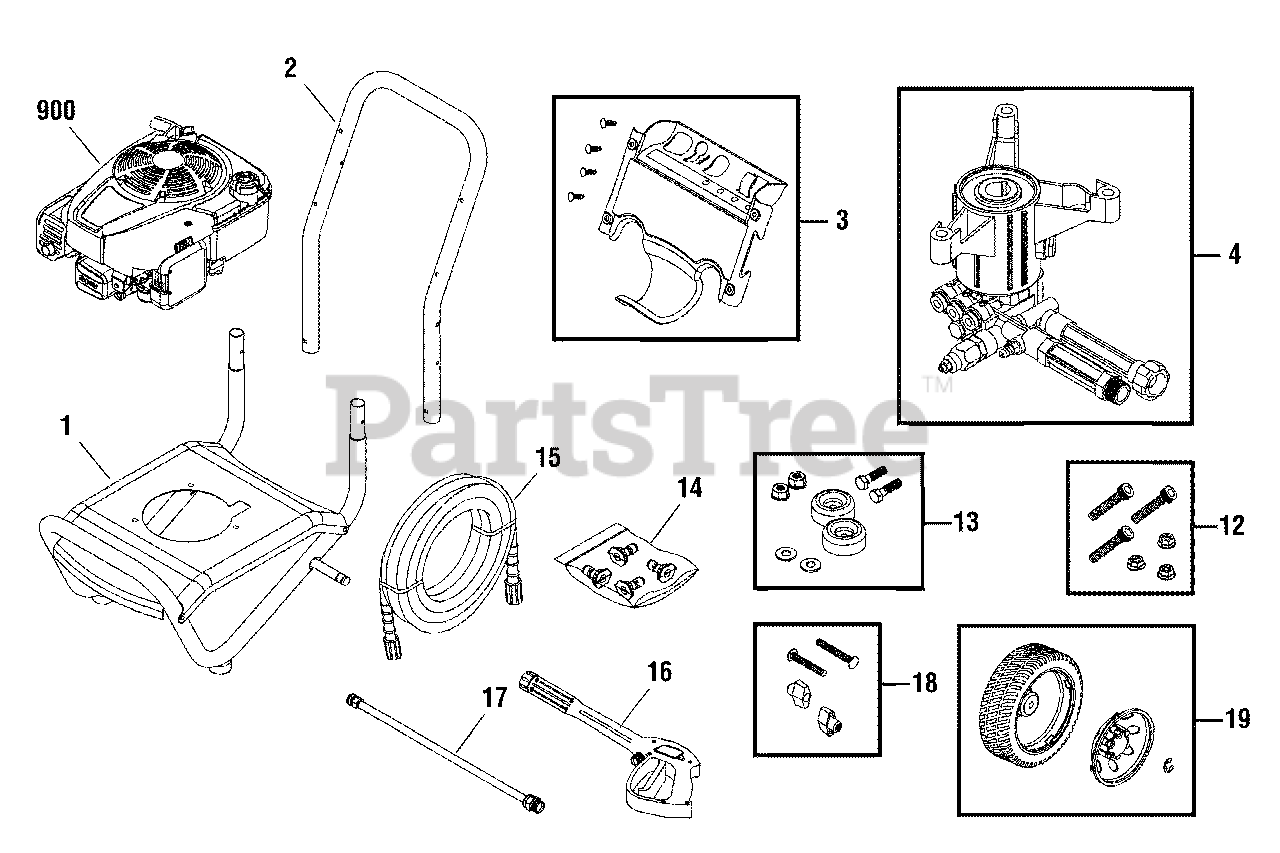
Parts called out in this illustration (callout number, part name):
2	HANDLE
12	KIT, Hardware, Pump Mounting
13	MOUNT, Vibration
14	KIT, QC Nozzles
15	HOSE
16	GUN
17	EXTENSION, QC
18	KIT, Hardware, Handle
19	KIT, Wheel
900	* ENGINE
